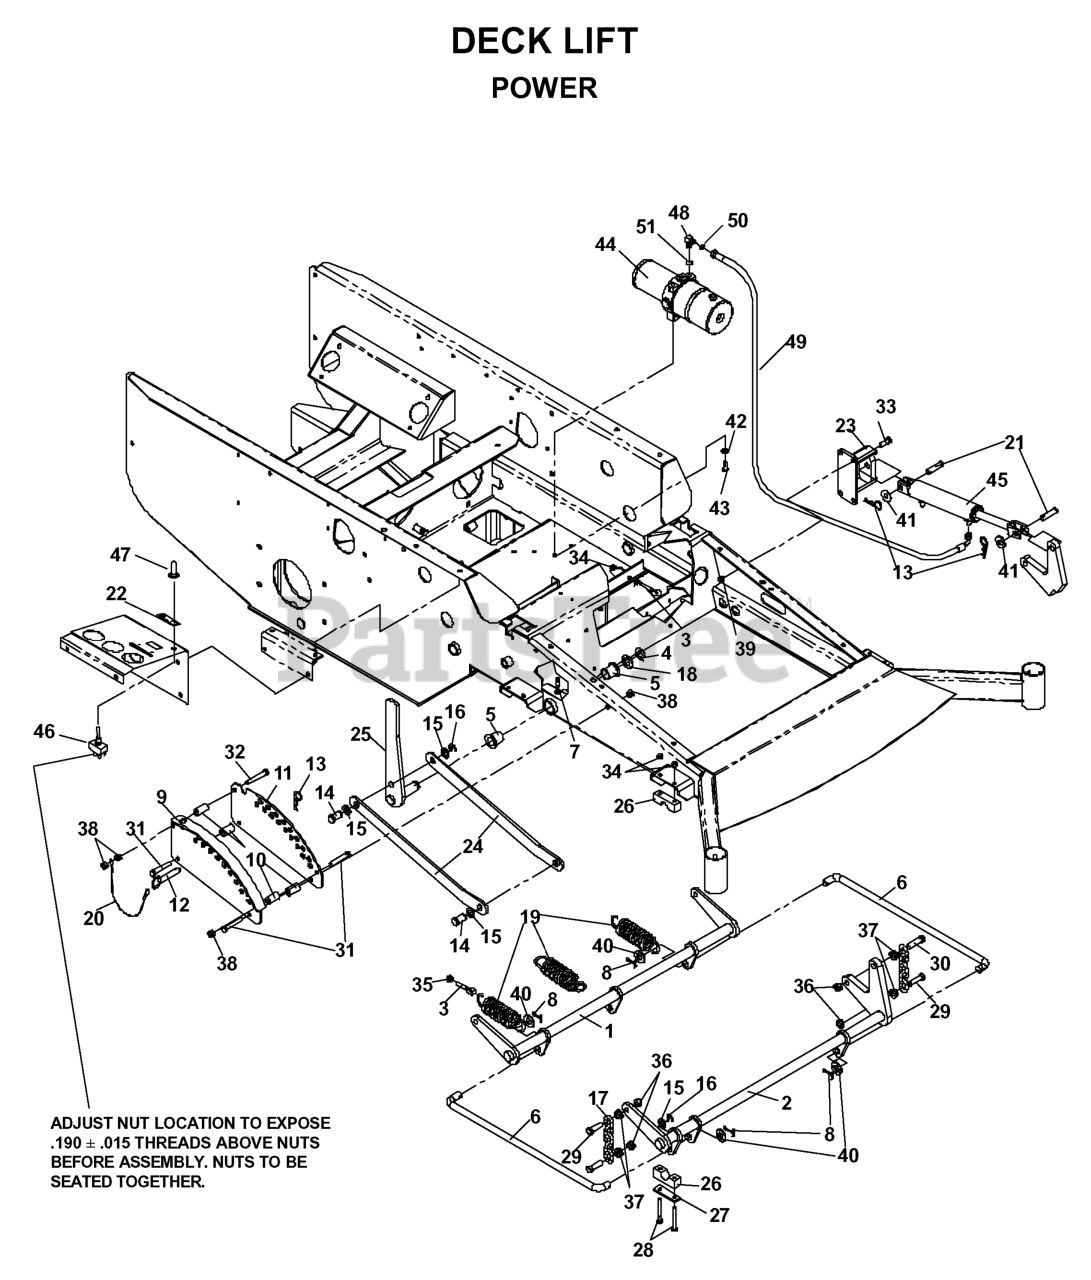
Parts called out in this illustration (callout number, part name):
1	SHAFT LIFT REAR
2	LIFT SHAFT WELDMT FRONT
3	EYEBOLT, RH
4	E-RING 7/8
5	BUSHING, FLANGED
6	CONNECTING LINK
7	GREASE ZERK LONG
8	COTTER PIN
9	ADJ. PLATE WLDMNT
10	DECK LIFT SPACER
11	ADJ. PLATE PAINTED
13	HAIRPIN #4
14	CLEVIS PIN
16	E-RING 5/8
17	LIFT CHAIN
18	BSHG .875 X 1.375 X .074 ZD
19	DECK LIFT SPRING
21	CLEVIS PIN 1/2 X 3/4
22	DECAL, LIFT SWITCH
23	CYLINDER MTG WLDMT
24	LIFT LINKAGE,PAINTED
25	LIFT LEVER
26	PILLOW BLOCK
27	REINFORCEMENT BAR
28	BOLT 5/16C X 2 1/2
29	HCS 7/16C X 1 1/2
30	HCS 7/16 - 14 X 1 3/4
31	HCS 3/8C X 2 1/4
32	HCS 3/8C X 2 1/2
33	HCS 3/8-16X1.GRD.5.ZD
34	NUT 5/16C CENTERLOCK
35	NUT 5/16C WHIZ
36	NUT 7/16C CENTERLOCK
37	NUT 7/16C WHIZ
38	NUT 3/8C CENTERBLOCK
39	NUT 3/8-16 NYLOC
40	WASHER 5/8 FLAT
41	WASHER 1/2 FLAT
42	SLW 3/8 STD
43	SCREW 3/8C X 3/4 HEX CAP
44	HYDRAULIC POWER UNIT
45	HYDRAULIC CYLINDER
47	SWITCH BOOT
49	HYDRAULIC HOSE ASSY
